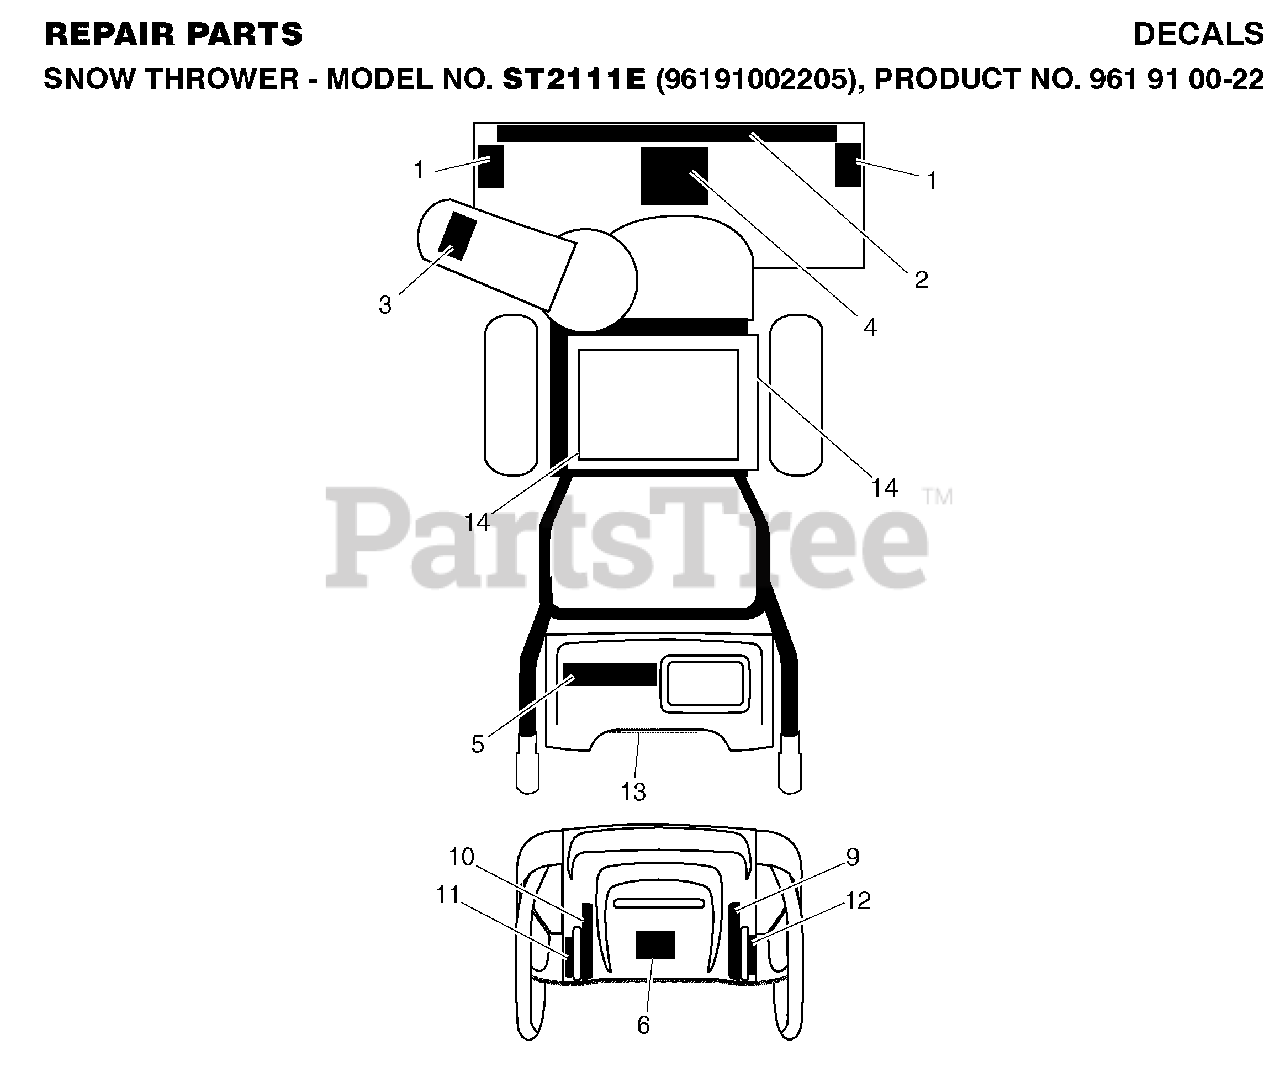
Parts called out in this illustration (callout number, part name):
1	DECAL.AUGER.SAFETY.
3	DECAL.CHUTE.SAFETY.
4	DECAL.AUGER."
6	DECAL.CONSOLE.INSTRUCTION
10	DECAL.REM.DEFLECTOR.LT
11	DECAL.POWER.STEER.LT.TRIG.INT
12	DECAL.POWER.STEER.RT.TRIG.INT
13	DECAL.FENDER
14	DECAL.BELT.GUARD.
